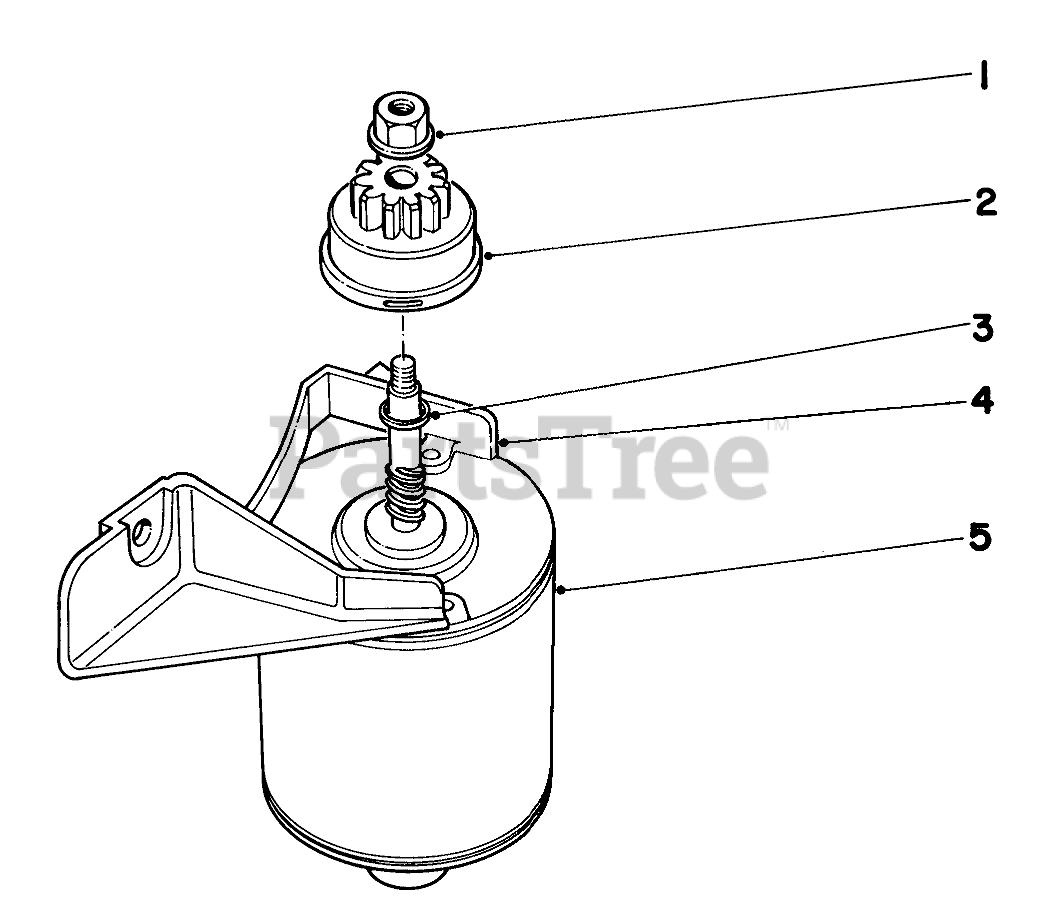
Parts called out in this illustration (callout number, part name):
1	NUT-HHF
2	Pinion Assemble
3	Spacer
4	Mounting Bracket
5	Starter Motor (Incl. Ref. #1-4)
